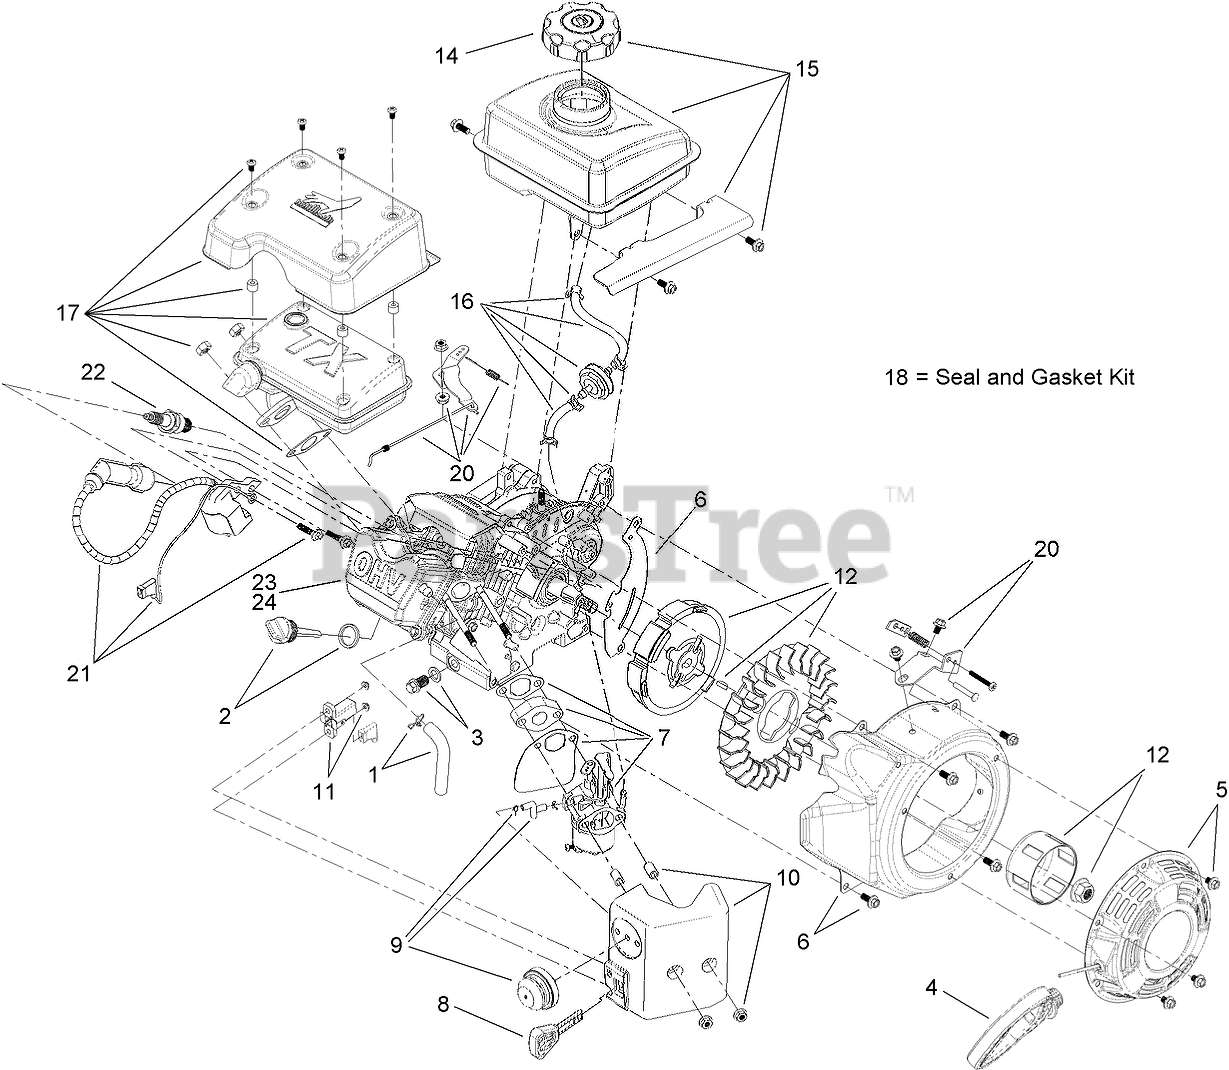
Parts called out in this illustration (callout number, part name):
1	BREATHER TUBE KIT
2	DIPSTICK AND O-RING KIT
3	DRAIN PLUG KIT
4	MITTEN GRIP KIT
5	RECOIL ASM KIT
6	BLOWER SHROUD KIT
7	COMPLETE CARB SERVICE KIT
7	Needle Rework Kit
7	CARB FLOAT AND NEEDLE KIT
8	KEY AND LANYARD KIT
9	PRIMER, BASE, LINE AND CLAMPS KIT
10	HEATER BOX AND HARDWARE KIT
11	SWITCH KIT
12	FLYWHEEL AND FAN KIT
14	FUEL CAP ASM KIT
15	FUEL TANK, CAP AND HARDWARE KIT
16	FILTER, FUEL LINE AND CLAMP KIT
17	MUFFLER KIT
20	GOVENOR ARM/SPRING/LINK AND HARDWARE KIT
21	IGNITION KIT
22	SPARK PLUG
23	VALVE COVER ASM
24	GASKET-COVER, VALVE
